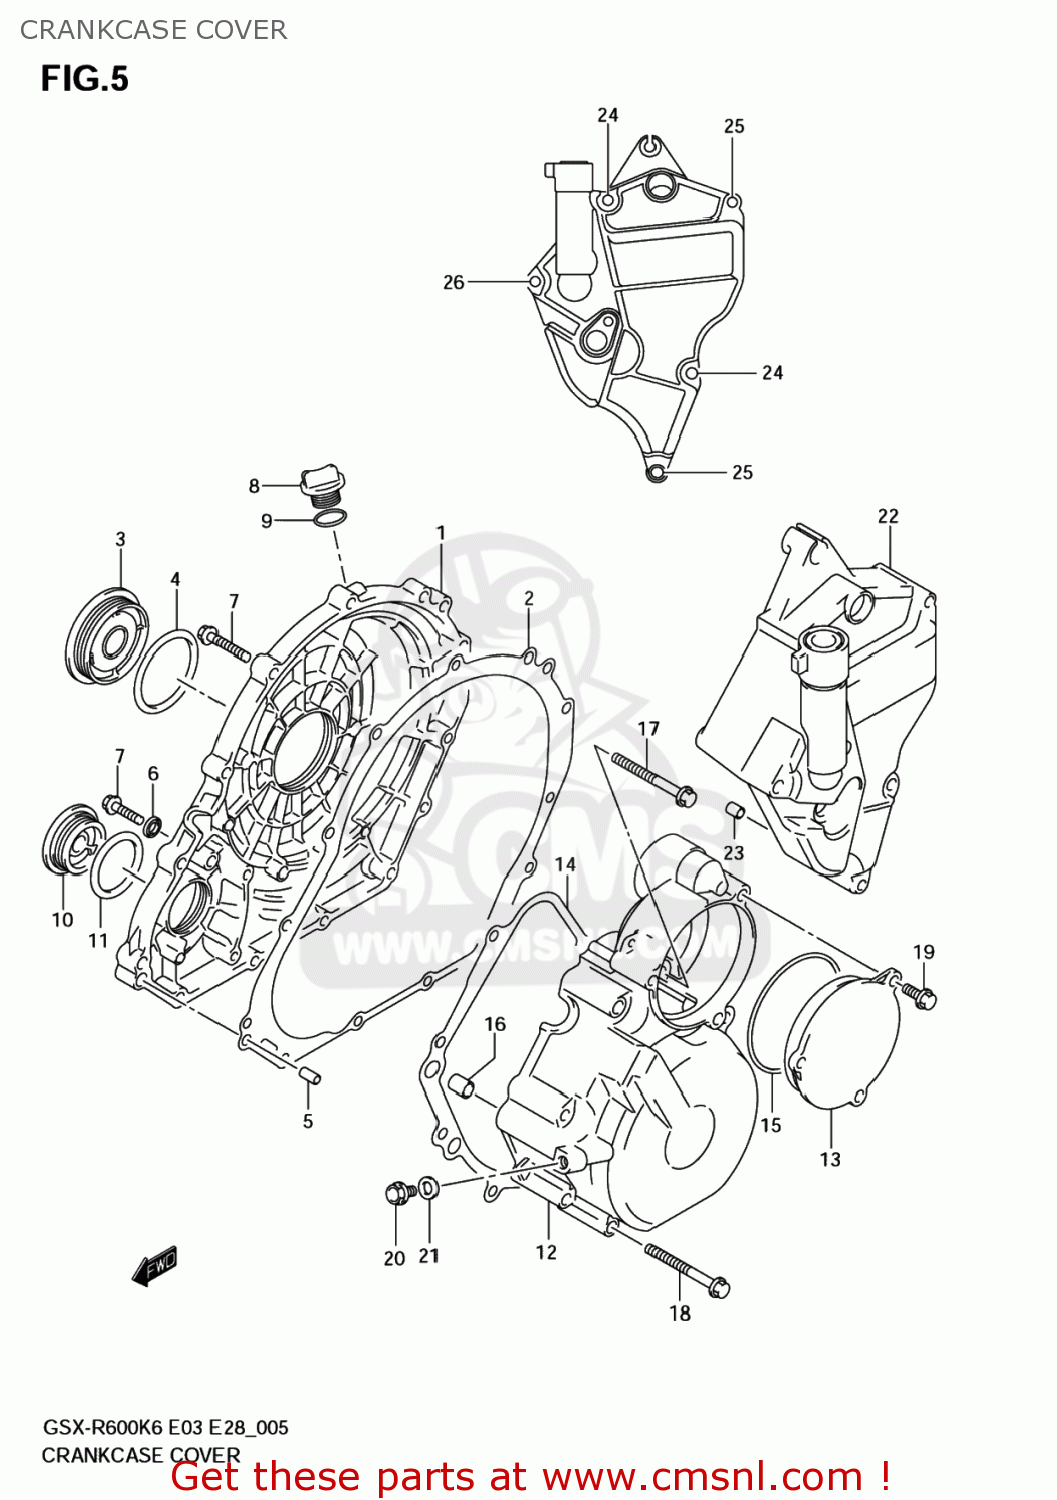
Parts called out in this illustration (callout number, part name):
1	COVER,CLUTCH
2	GASKET,CLUTCH COVER (NAS)
3	CAP,CLUTCH RELEASE ADJUST
4	O RING(D:2.4,ID:52.6)
5	PIN
6	GASKET(5.8X13X1.2) (NAS)
7	BOLT(6X30)
8	PLUG,ENGINE OIL FILLER
9	O RING(D:3.1,ID:16.8)
10	PLUG
11	O RING(D:3.1,ID:32.7)
12	COVER,GENERATO
13	CAP,STARTER IDLE GEAR
14	GASKET,GENERATOR COVER (NAS)
15	O RING(D:2.6,ID:67.1)
16	PIN
17	BOLT(6X25)
18	BOLT(6X50)
19	BOLT(6X16)
20	BOLT(6X12)
21	GASKET(6.2X13X1.2) (NAS)
22	COVER,ENGINE SPROCKET
23	PIN
24	BOLT(6X45)
25	BOLT(6X65)
26	BOLT(6X75)
